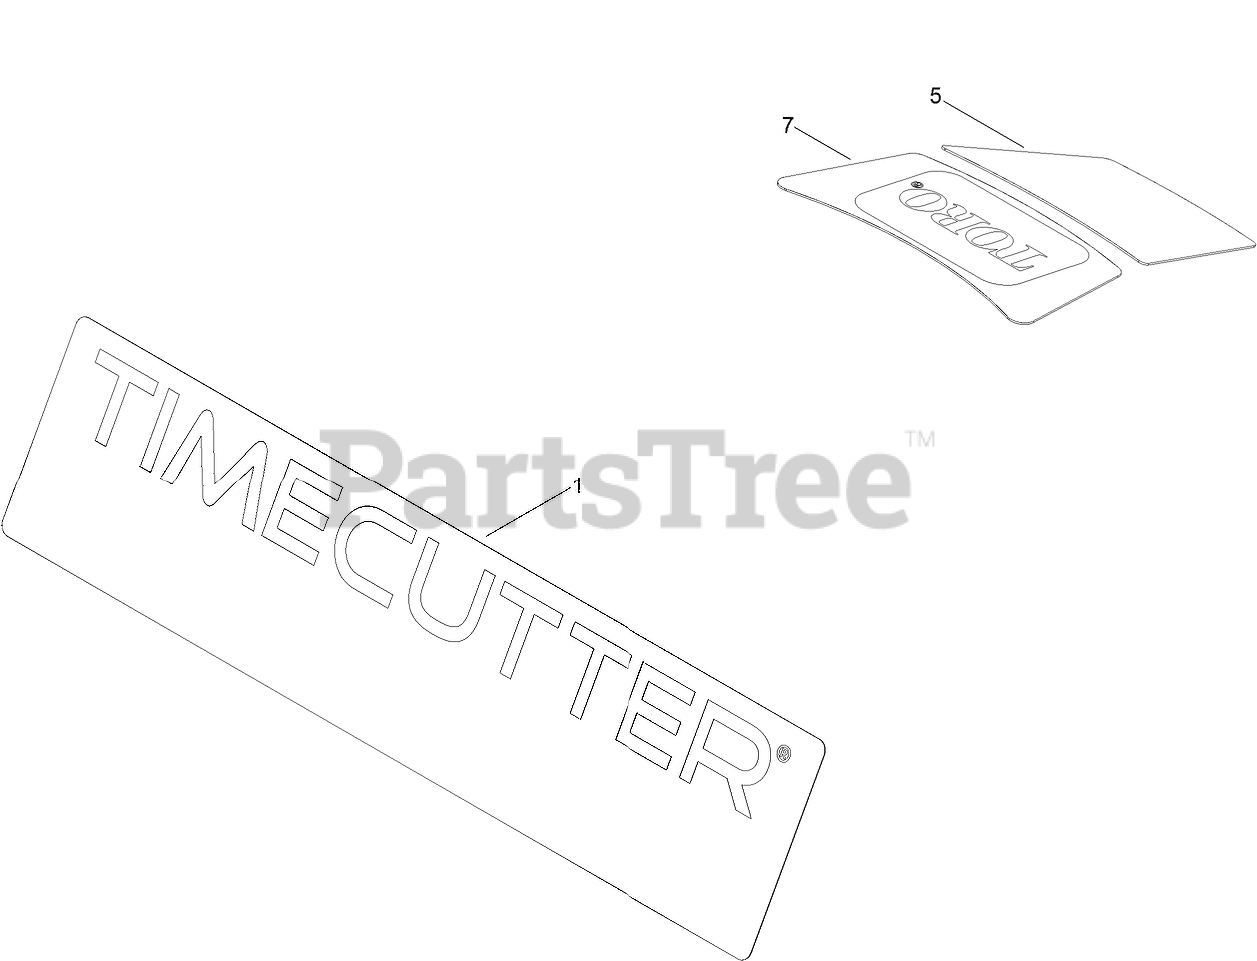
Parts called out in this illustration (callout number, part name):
1	DECAL-TIMECUTTER
5	DECAL-DISPLACEMENT, ENGINE
7	DECAL-ENGINE
